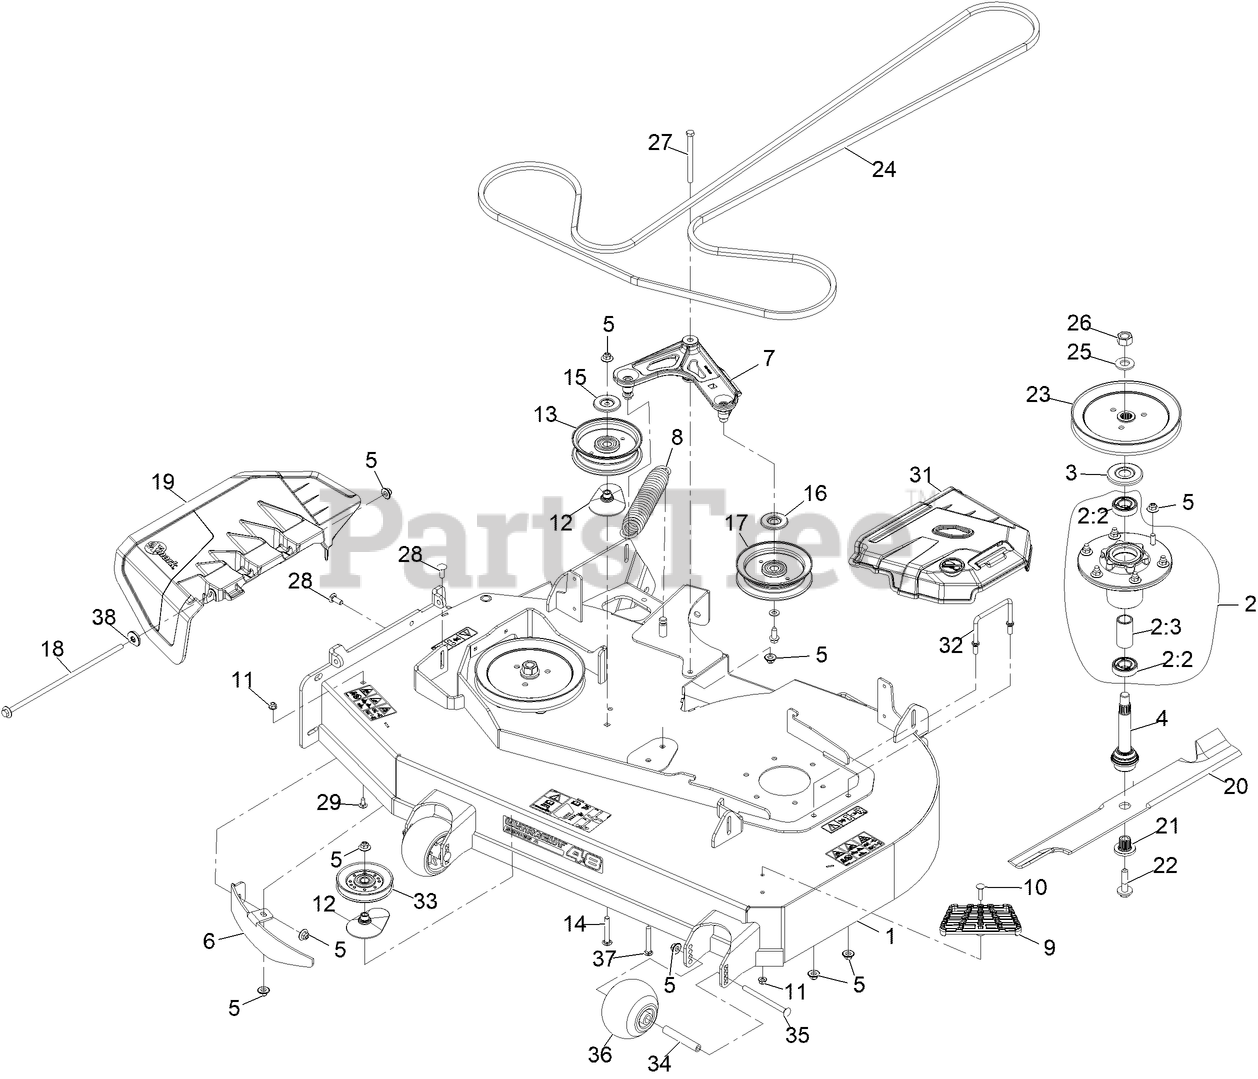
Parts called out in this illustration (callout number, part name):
1	ASM, 48" DECK W/DECALS
2	ASM-CUTTER HSG WITH BEARINGS
2:2	BEARING-BALL
2:3	SPACER-BEARING
3	GUARD-BEARING, TOP
4	ASM-SPINDLE AND SEAL
5	Nut-Nyloc 3/8-16 Flg
6	Baffle-Discharge 48 2Blade
7	ASM-IDLER ARM W/BEARINGS
8	SPRING-EXTENSION
9	STEP-DECK
10	Bolt-Carriage 5/16-18 X 1 1/4
11	NUT-HF, NI
12	SPACER-PULLEY
13	IDLER-PULLEY, FLAT 5.00X1.31
14	SCREW-CARR
15	SHIELD-DUST
16	SHIELD-GUARD, DUST
17	IDLER-PULLEY, FLAT
18	Pin, Chute
19	Chute-Deck Discharge
21	BUSHING,SPLINED
22	SCREW,SEMS 1/2-20 X 2.19
23	SHEAVE-BLADE DRIVE, 8.40
26	NUT-HEX
27	SCREW-HH
28	SCREW-CARR
29	SCREW-CARR
31	SHIELD, LT
32	WIREFORM-COVER
33	Idler - V 4.13 Eod-A
34	SPACER-AXLE
35	BOLT-CARR
36	ROLLER-SCALP, ANTI
37	SCREW-CARR
38	Retainer, Chute
